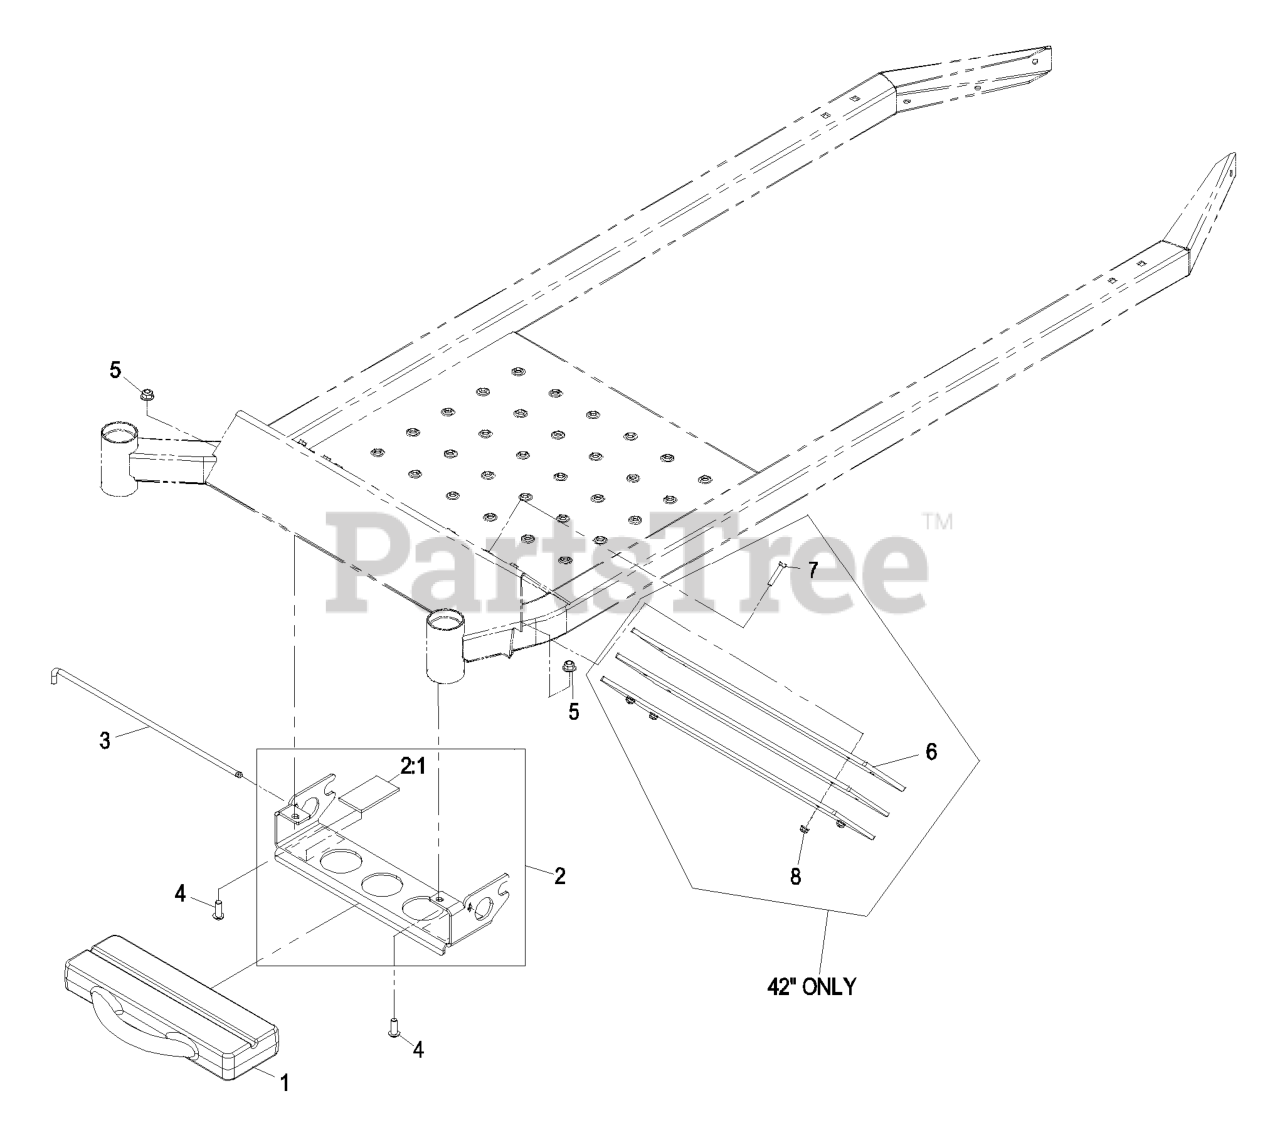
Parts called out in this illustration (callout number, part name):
2	BRACKET ASM
2:1	CUSHION-RUBBER
3	PIN-WEIGHT
4	SCREW-HSBH
5	NUT-HF, NI
6	WEIGHT,BAGGER
7	SCREW-HH
